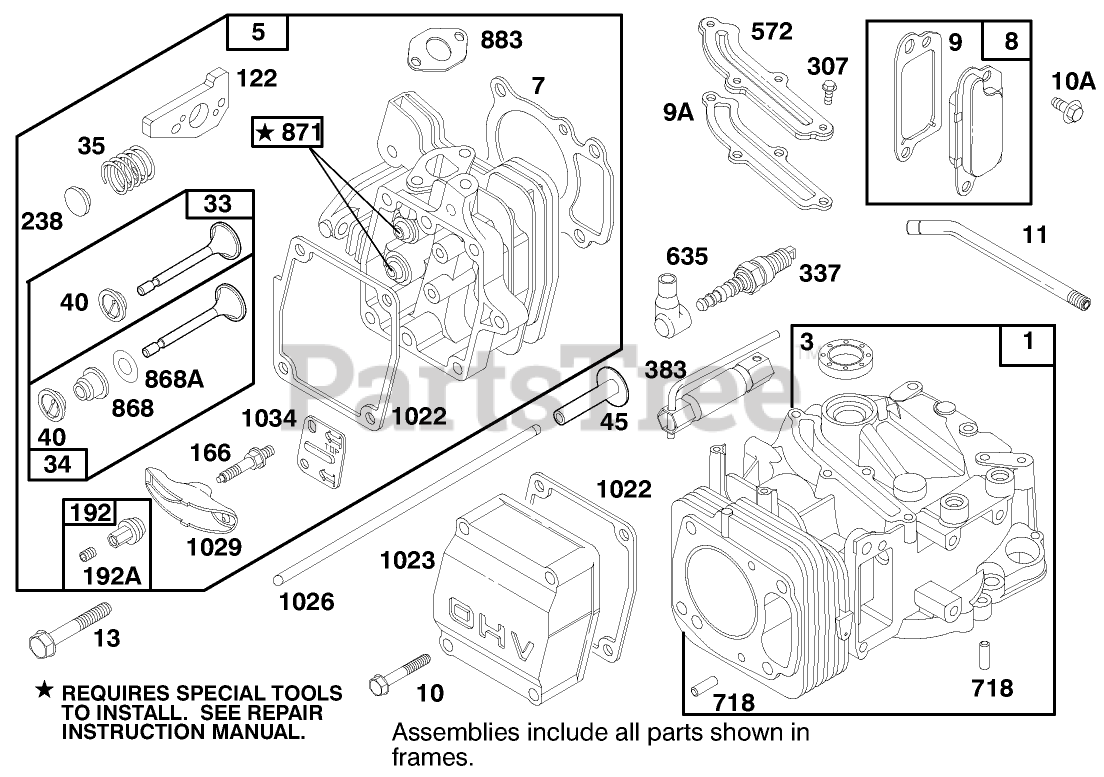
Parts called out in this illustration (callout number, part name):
98A	SPEED ADJUST. SCREW ASM
163	AIR CLEANER GASKET
188	Plug-Pipe
201	GOVERNOR LINK
209	GOVERNOR SPRING
529	TUBE - BREATHER
535	FILTER ELEMENT
618	RETURN SPRING
620	CARBURETOR BRACKET
621	STOP SWITCH
966	AIR CLEANER BASE
968	AIR CLEANER COVER
969	AIR CLEANER SCREW
971	AIR CLEANER SCREW
